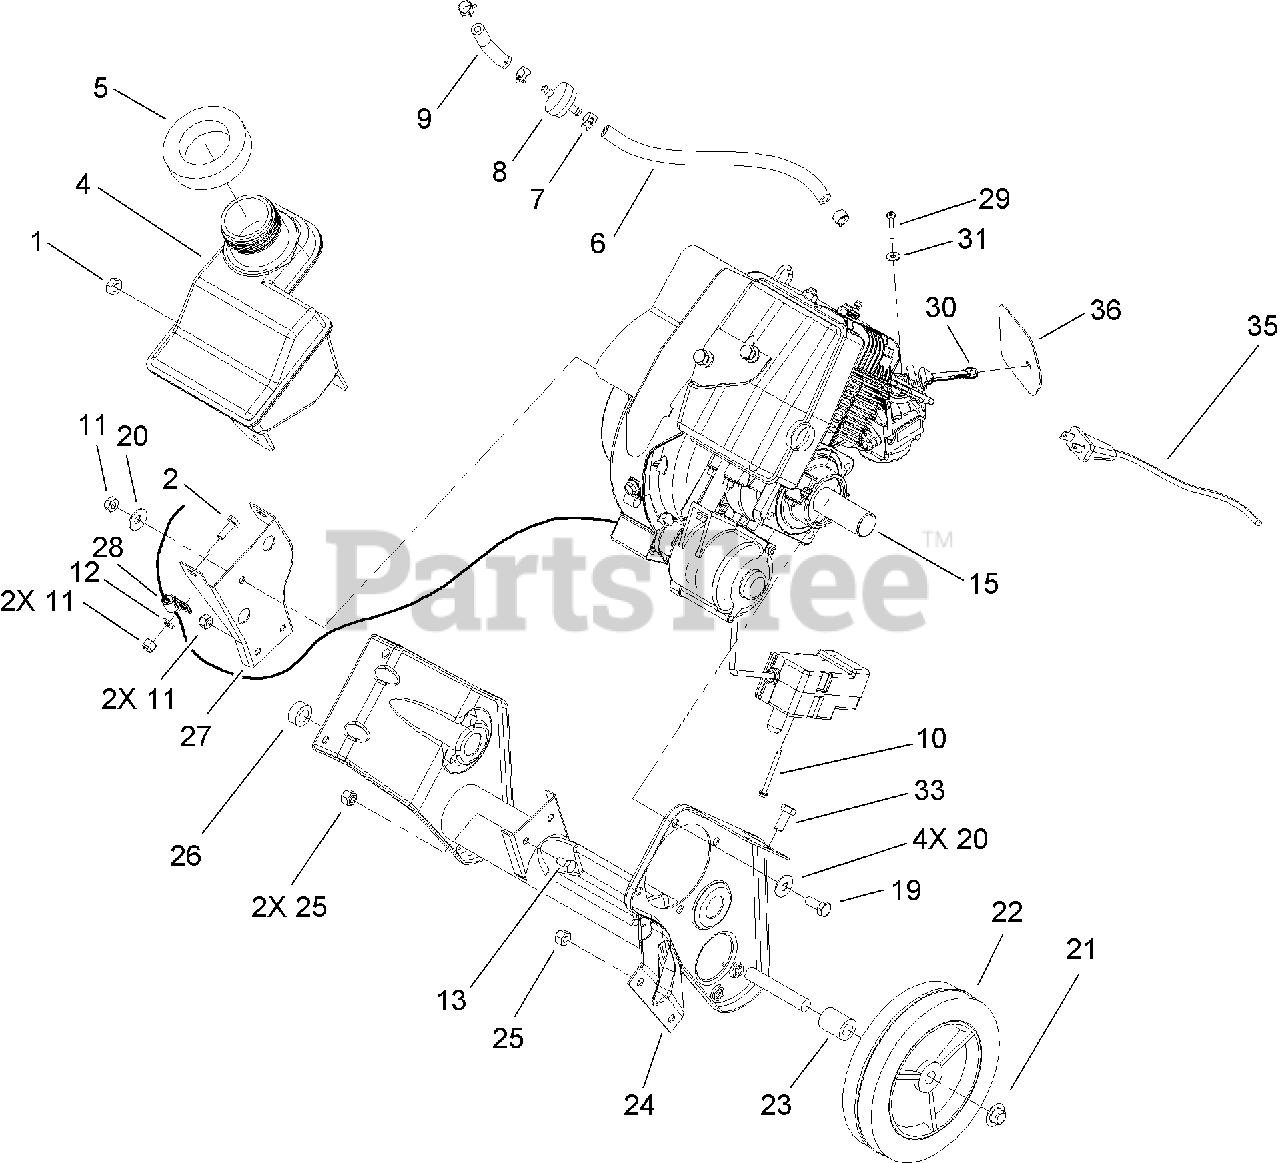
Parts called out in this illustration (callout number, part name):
1	NUT-LOCK, CONE
2	SCREW-HH
5	SEAL-FOAM
6	LINE-FUEL
8	FILTER-FUEL
9	HOSE-FUEL
10	SCREW-PLASTITE
11	NUT-LOCK, NI
12	WASHER-FLAT
13	SCREW-HH
19	SCREW-HH
20	WASHER-BELLEVILLE
23	SPACER-WHEEL
25	NUT-LOCK, NI
26	SPACER-WHEEL
27	BRACKET-SUPPORT, RECOIL
29	SCREW-PPH, PLASTITE
30	LEVER-CHOKE
31	WASHER-FLAT
33	SCREW-HH
35	CORD-ELECTRIC
36	SHIELD-HOLE, CHOKE
